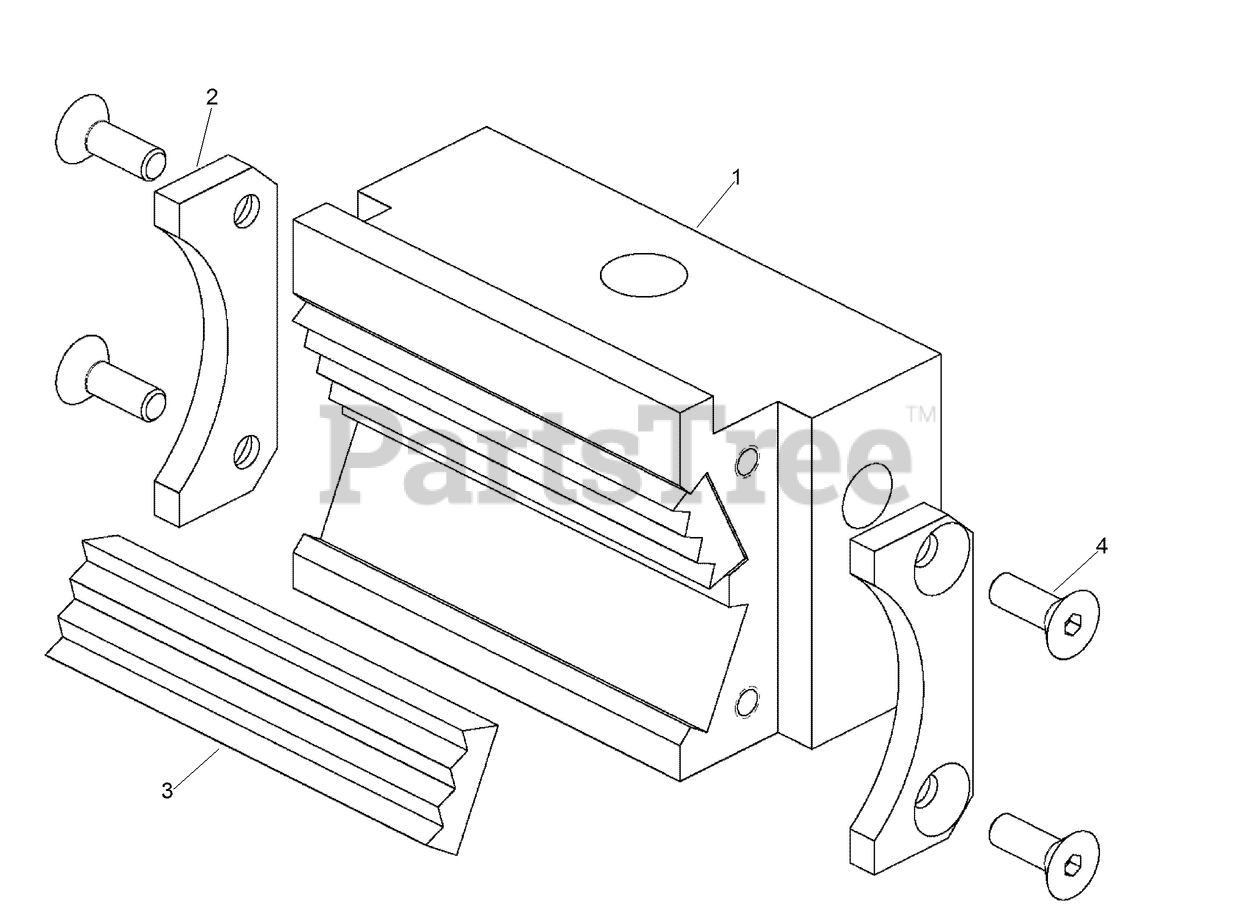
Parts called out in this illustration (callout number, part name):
1	HOLDER-DIE, MOVING
2	RETAINER-DIE
3	TONG-DIE
4	SCREW - Hex Soc Flh 1/4 UNRC x .75 ZND
